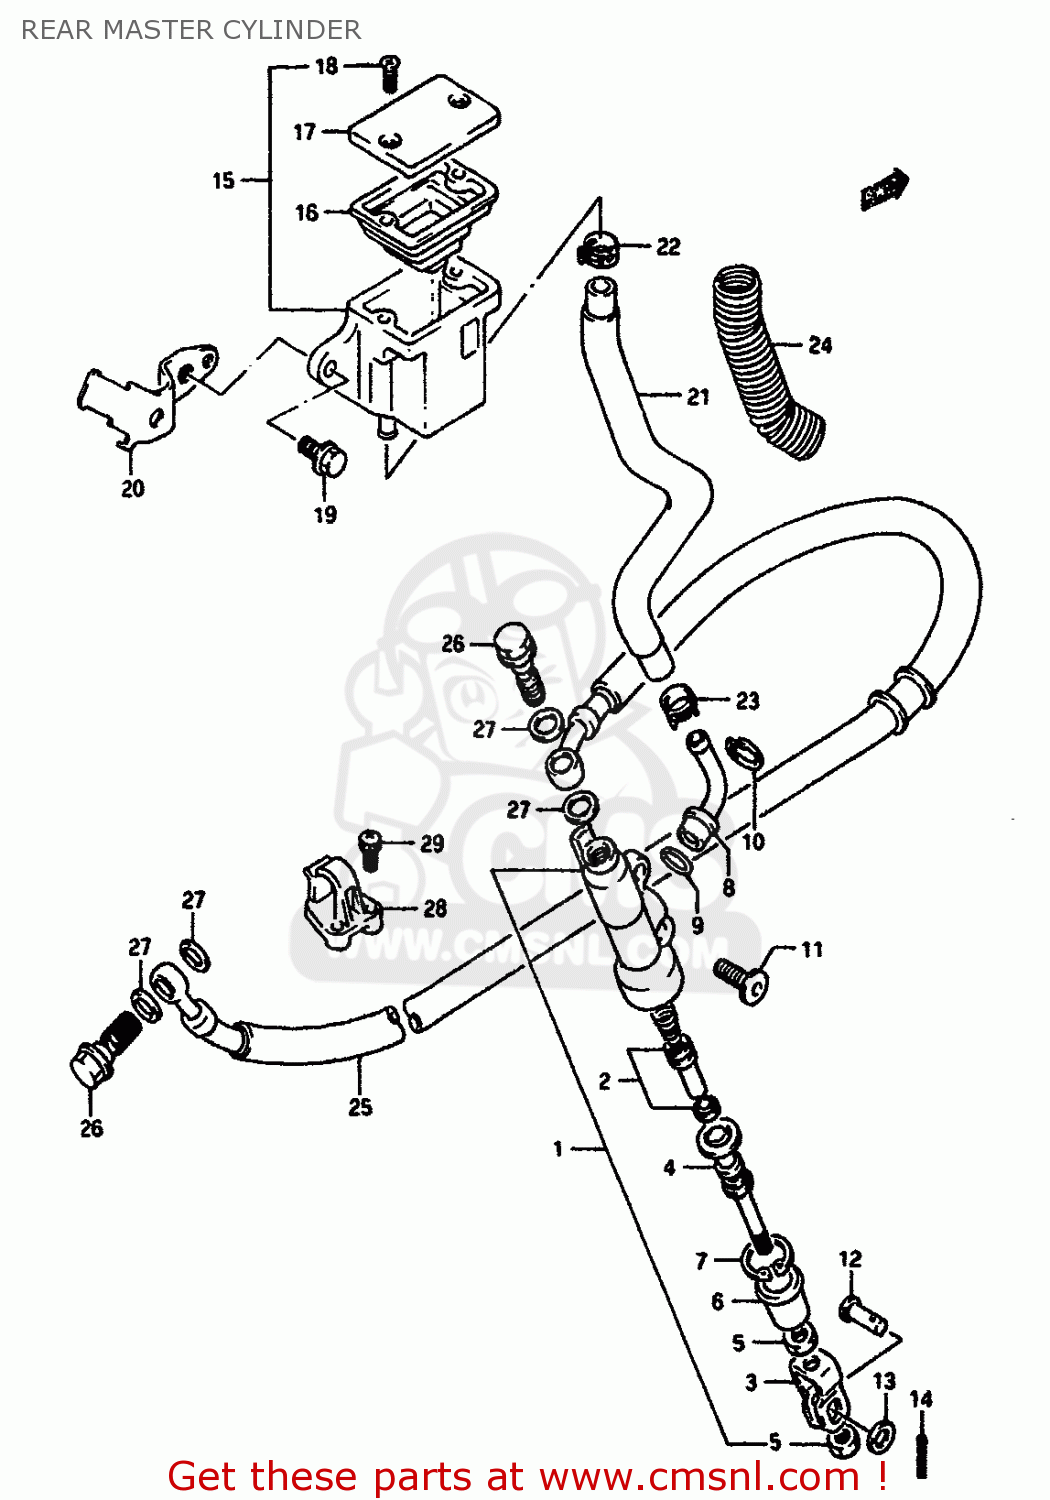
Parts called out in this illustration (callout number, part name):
1	CYLINDER ASSY,RR MASTER
2	PISTON/CUP SET
3	YOKE
4	ROD,PUSH
5	NUT
6	BOOT
7	CIRCLIP
8	CONNECTOR
9	O RING
10	CIRCLIP
11	BOLT(6X18)
12	PIN
13	WASHER
14	PIN
15	TANK ASSEMBLY,RESERVOIR
16	DIAPHRAGM
17	CAP
18	SCREW
19	BOLT
20	PLATE COMP,RESERVOIR T
21	HOSE COMP,RESERVOIR TANK
22	CLIP
23	CLAMP
24	SHIELD,RESERVOIR TANK HOSE
25	HOSE COMP,REAR BRAKE
26	BOLT UNION
27	WASHER(10X15X1.5)
28	GUIDE,RR BRAKE HOSE
29	SCREW
